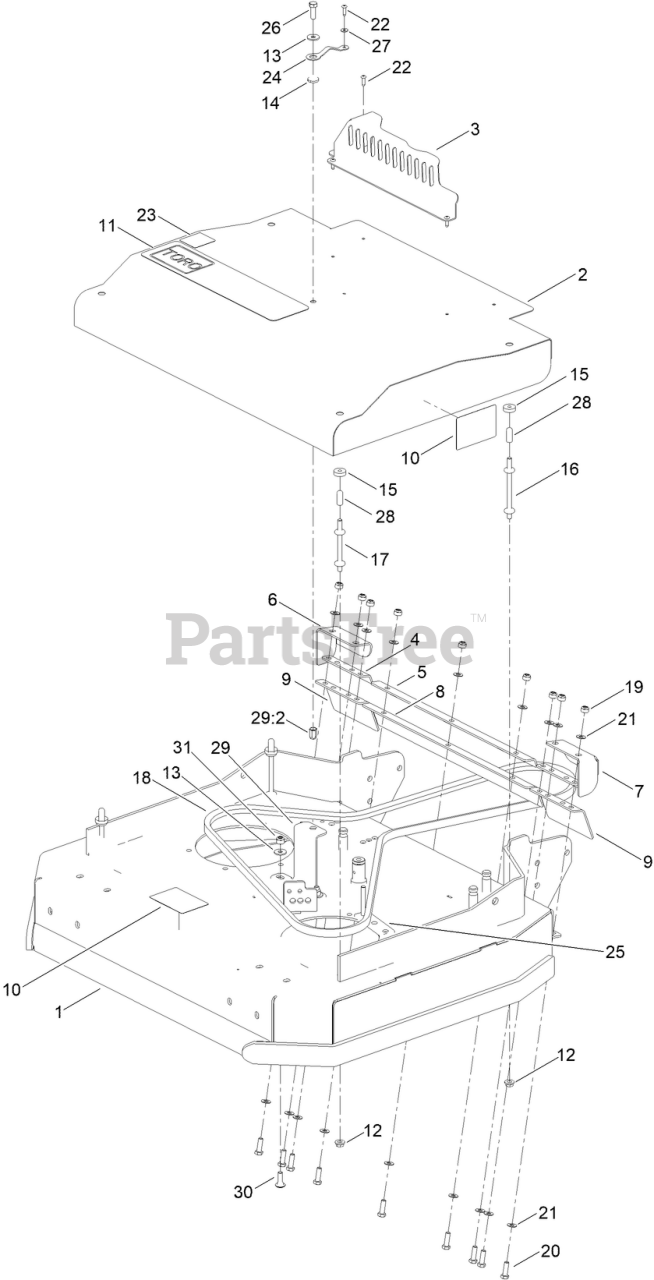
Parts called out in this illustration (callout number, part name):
1	32 INCH DECK ASM
2	COVER-DECK
3	GUARD-PIPE, EXHAUST
4	BRACKET-DEFLECTOR, SIDE
5	BRACKET-DEFLECTOR, CENTER
6	GUARD-DISCHARGE, RH
7	GUARD-DISCHARGE, LH
8	DEFLECTOR-CENTRE, RUBBER
9	DEFLECTOR-SIDE, RUBBER
10	DECAL-DANGER, CE
12	NUT-HF
13	WASHER
14	NUT-RETAINER
15	WASHER
16	STUD-SHIELD, BELT (LONG)
17	STUD-SHIELD, BELT (SHORT)
18	BELT-V
19	NUT-NYLOC
20	SCREW-HH
21	WASHER
22	RIVET
23	DECAL-NOISE
24	LANYARD-3 INCH
25	GUIDE-BELT
26	SCREW-HH
27	WASHER
28	CAP-END, RUBBER
29	BRACKET-GUARD
29:2	NUT-RIVET
30	BOLT-COACH
